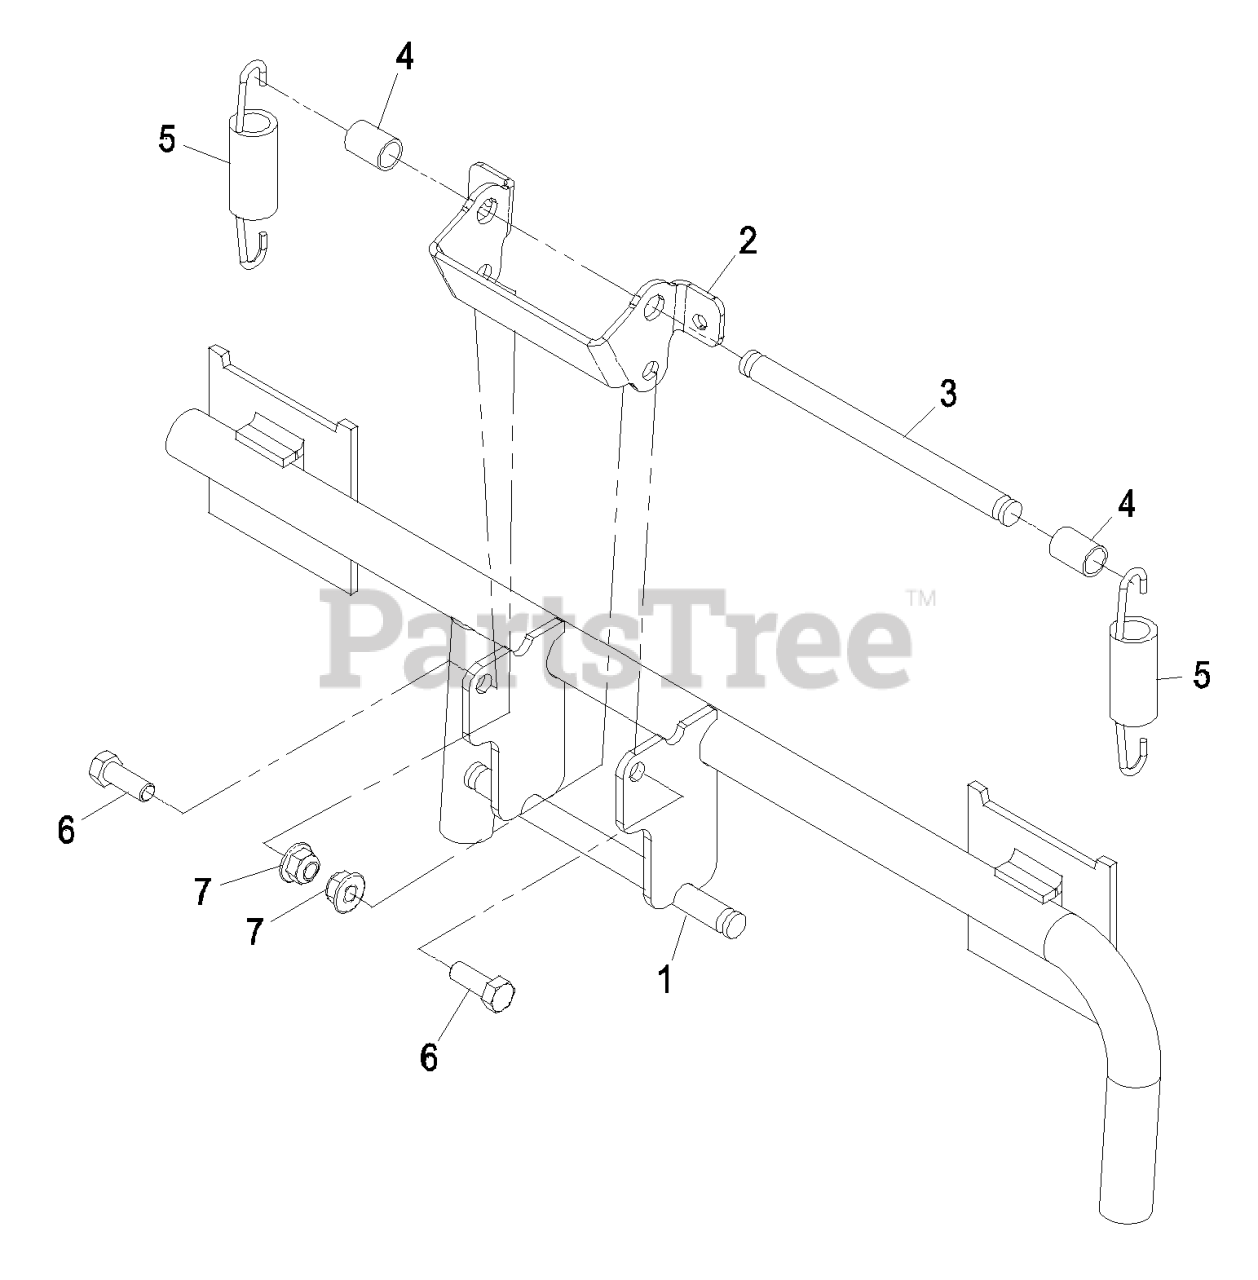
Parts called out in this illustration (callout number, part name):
1	WLD,BAGGER FRAME
2	HINGE,BAGGER TOP
3	PIN-SPRING
5	SPRING-EXTENSION
6	SCREW-HH
7	NUT-HF, NI
